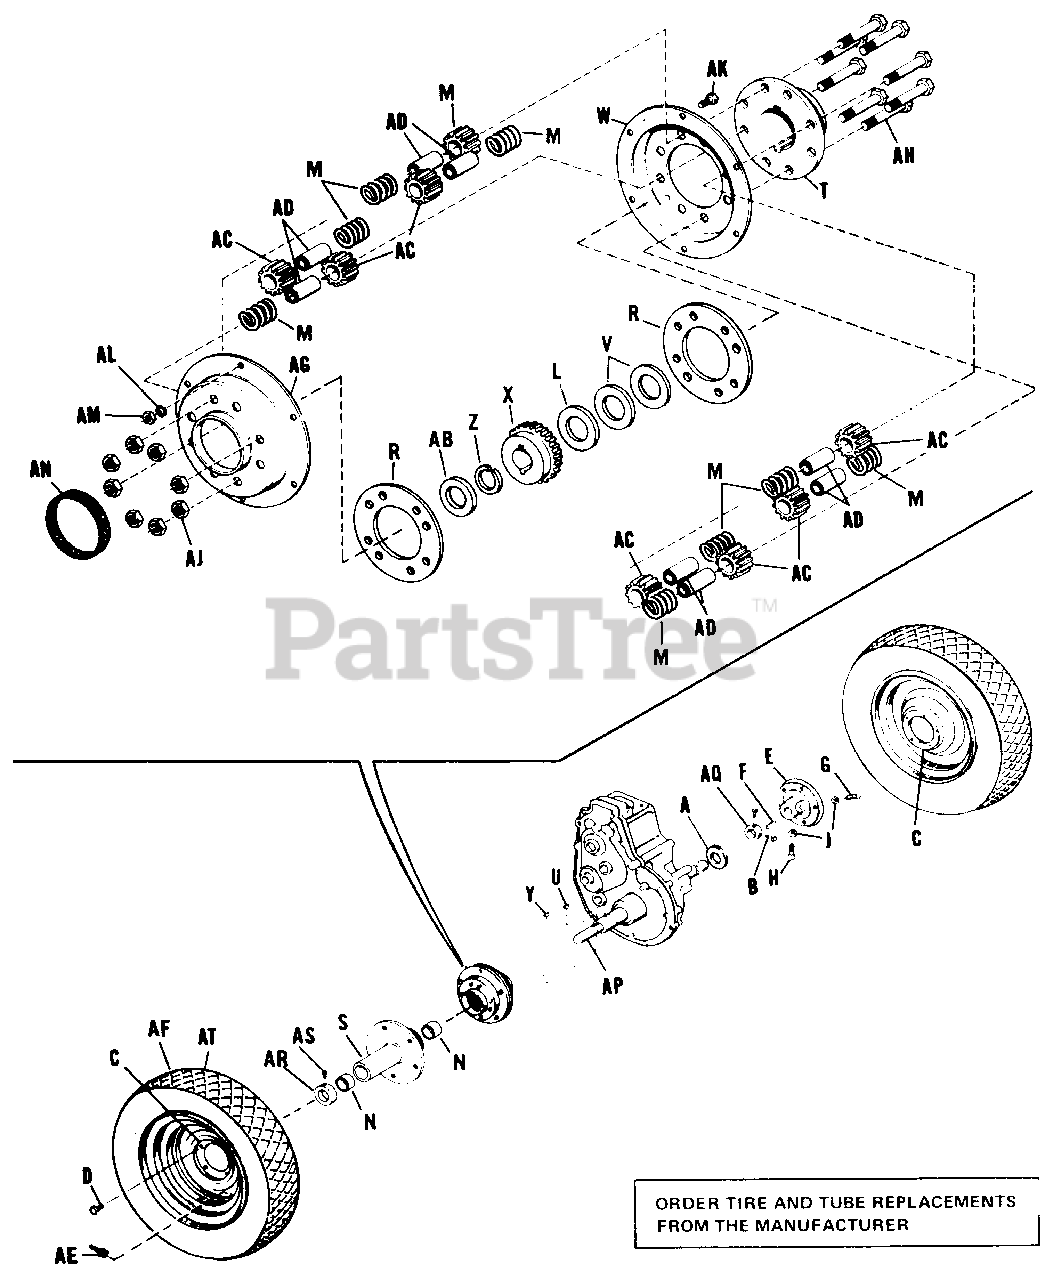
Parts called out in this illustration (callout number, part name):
B	Set Screw, 5/16"-18 x 3/8"
C	Wheel Drive
E	L.H. Wheel Hub
G	Set Screw, 3/8"-16 x 1-1/2"
H	Set Screw, 3/8"-16 x 1"
J	Hex Jam Nut, 3/8"-16
L	Axle Washer
R	Ring Spacer
S	Wheel Hub Assy.
T	Differential Carrier
V	Axle Washer
W	Differential Cover
X	Differential Gear
Y	Hi-Pro Key
Z	Retaining Ring
AA	Tube (For Service Only)(14 H.P.)
AA	Tube (For Service Only)(10 H.P.)
AB	Axle Washer
AC	Differential Pinion
AD	Pinion Differential Cover
AE	Valve Stem
AF	Wheel & Tire Assy. (14 H.P.)
AF	Wheel & Tire Assy. (10 H.P.)
AG	Differential Cover
AH	Hex. Cap Screw, 3/8"-16 x 2-1/2"
AJ	Full Lock Hex. Nut, 3/8"-16
AK	Hex. Cap Screw, 1/3"-20 x 5/8"
AL	Lock Washer, 1/4"
AM	Full Hex. Nut, 1/4"-20
AN	Differential Cover Seal
AP	Rear Axle
AQ	Axle Collar
AR	Axle Collar
AS	Set Screw, 5/16"-18 x 3/8"
AT	Tire 10-1/2" x 12 (14 H.P.)
AT	Tire 10-1/2" x 12 (10 H.P.)
